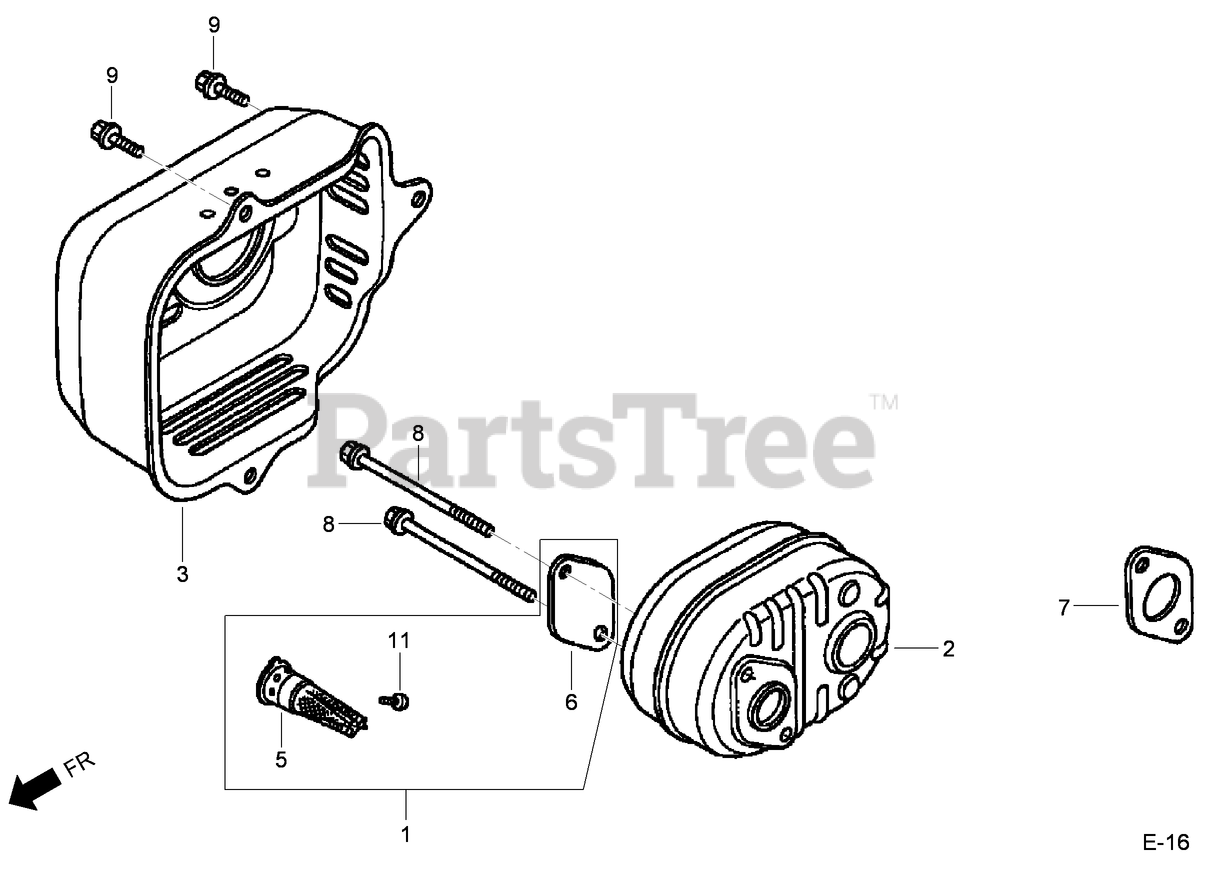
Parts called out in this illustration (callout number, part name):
1	SPARK ARRESTER KIT (Optional Equipment)
2	MUFFLER
3	PROTECTOR-MUFFLER
5	ARRESTER-SPARK (Optional Equipment)
6	PLATE-NUMBER, ARRESTER (Optional Equipment)
7	GASKET-MUFFLER (Optional Equipment)
8	BOLT-FLANGE (6X79) (C T200)
9	BOLT-FLANGE (6X12) (C T200)
11	SCREW-TAPPING (4X6) (Optional Equipment)
